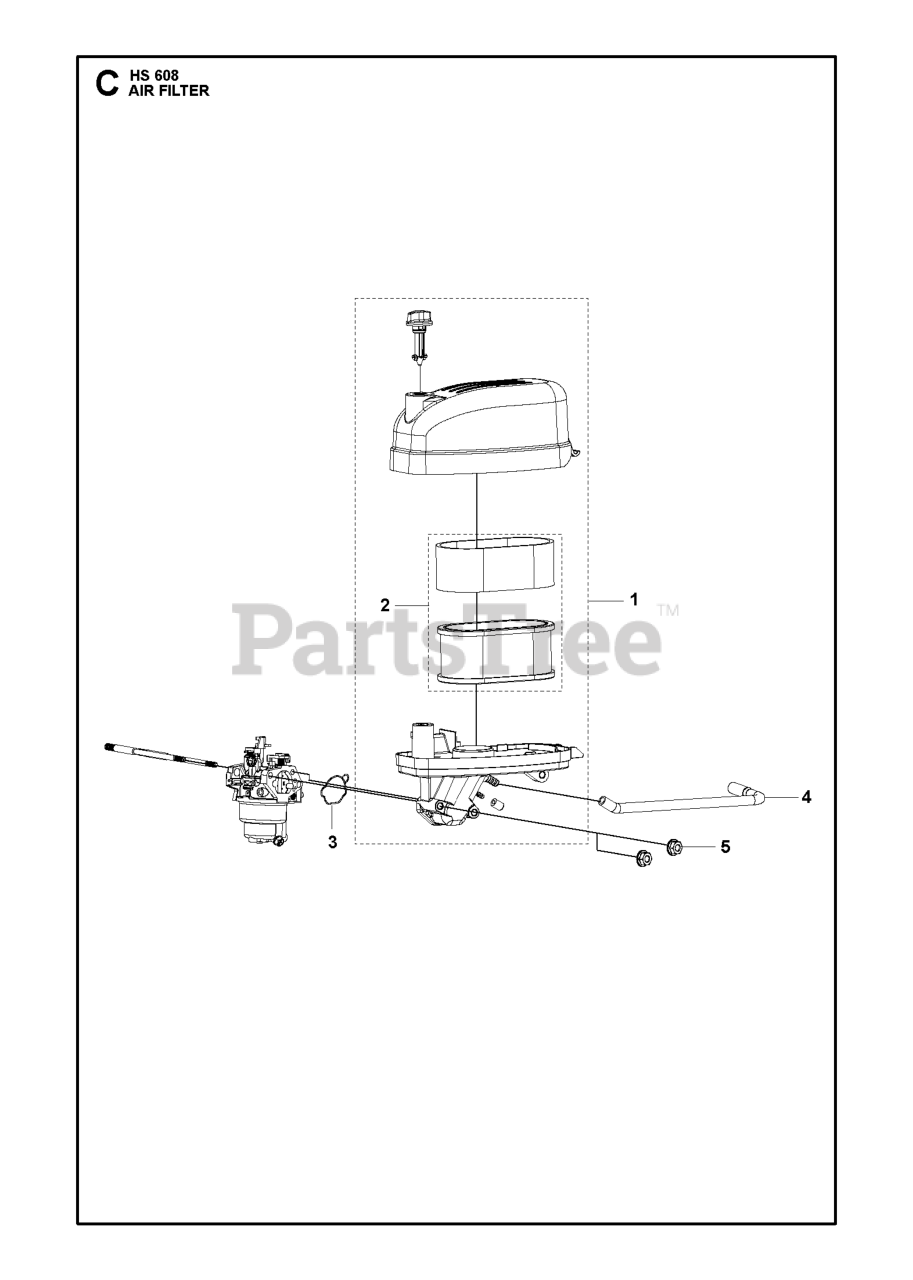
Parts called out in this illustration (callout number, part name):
1	AIR FILTER ASSY
2	AIR FILTER ELEMENT
3	GASKET CARBURETTOR GASKET
5	NUT GB/T 6177.1: M6
